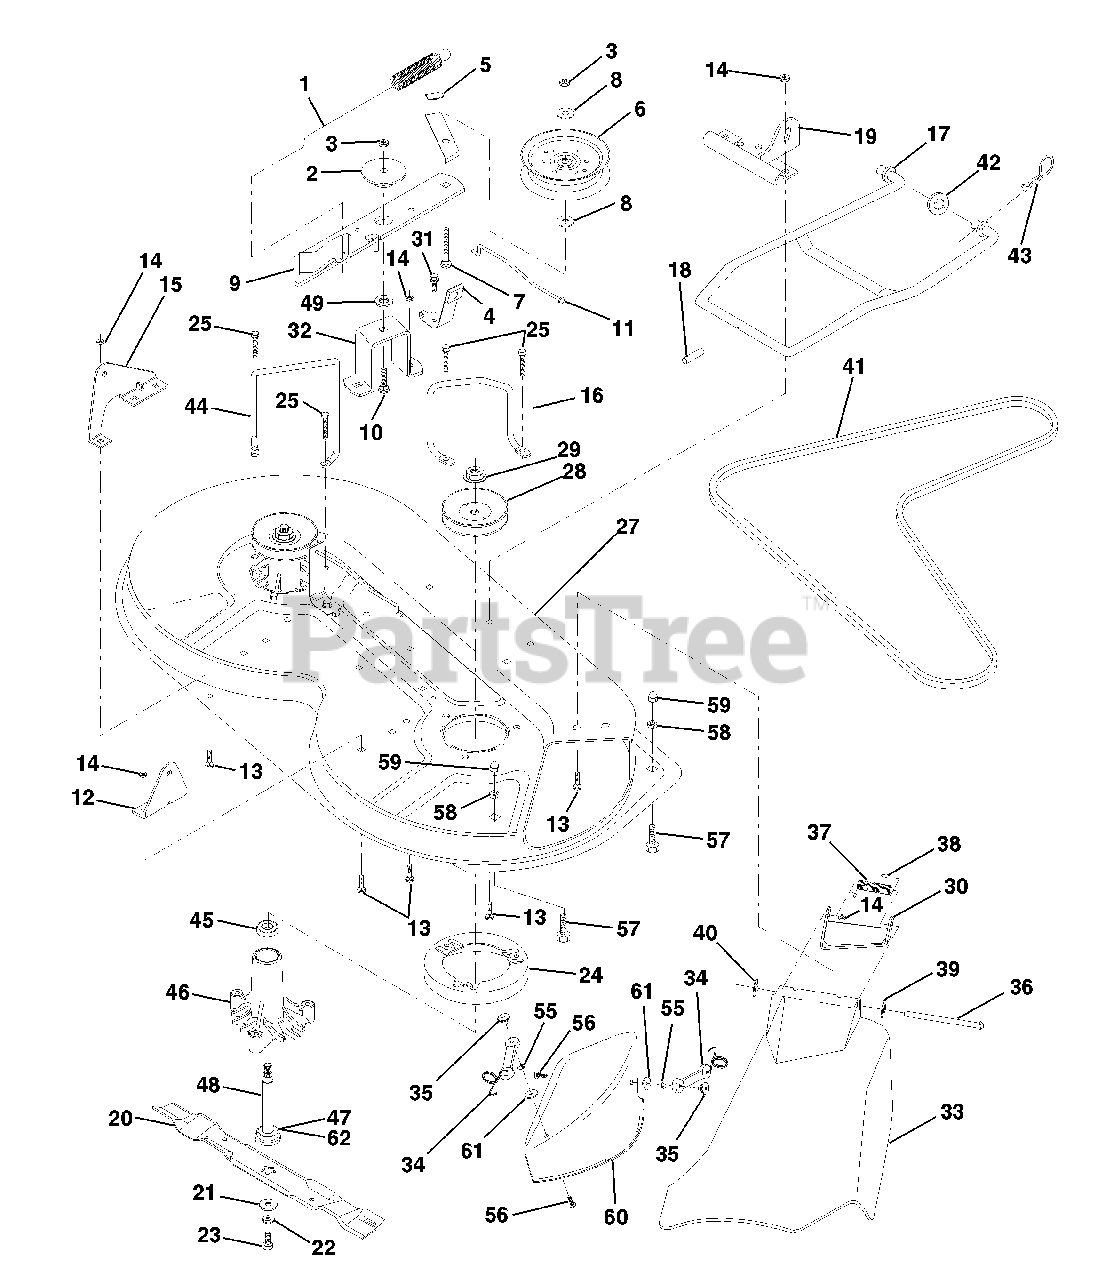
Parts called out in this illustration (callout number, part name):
1	Spring, Mower Clutch
2	Spacer, Retainer
3	Nut, Crownlock 3/8-16
4	Brake Asm.
5	Guide, Belt Idler
6	Pulley, Flat Idler
7	Bolt, Carr. 3/8-16 x 1-3/4 Gr. 5
8	Washer 13/21 x 7/8 x 10 Ga.
9	Arm Asm., Idler Mower
10	Bolt, Carriage 3/8-16 x 1-1/4
11	Rod, Brake
12	Bracket, Lift R. H. Rear
13	Bolt, Carriage 5/16-18 x 3/4
14	Nut, Crownlock 5/16-18
15	Bracket, Lift L. H. Rear
16	Keeper, R. H.
17	Link, Asm. Mower Stabilizer
18	Pin, Drive
19	Bracket, Asm. Front
20	Blade Mulching
21	Washer, Hard
22	Washer, Lock 3/8
23	Bolt 3/8-24 x 1-1/4 Gr. 8
24	Stripper
25	Screw Thdrol Wsh Hd
27	Deck Assembly
28	Pulley, Mandrel
29	Nut, Flangelock 9/16
30	Bracket, Asm. Deflector
31	Screw, Hex Wsh. Thdrol. 5/16-18 x 1/2
32	Arm, Support Idler Mower
33	Deflector
34	Latch Asm, Bagger/Mulch
35	Nut, Weld
36	Rod, Hinge
37	Spring, Torsion Deflector
38	Cap, Sleeve
39	Washer 11/32 x 5/8 x 16 Ga.
42	Washer 11/32 x 5/8 16 Ga.
43	Retainer, Spring
44	Keeper, L. H.
46	Housing Mandrel Vented
48	Shaft, Mandrel
49	Washer, Hardened
55	Washer, Lock
56	Screw
57	Bolt, Fin Hex 5/16-18 x 1
58	Nut, Nylon Insert
59	Nut, Acorn Hex 5/16 x 18
60	Cover, Mulching
62	Washer Felt
